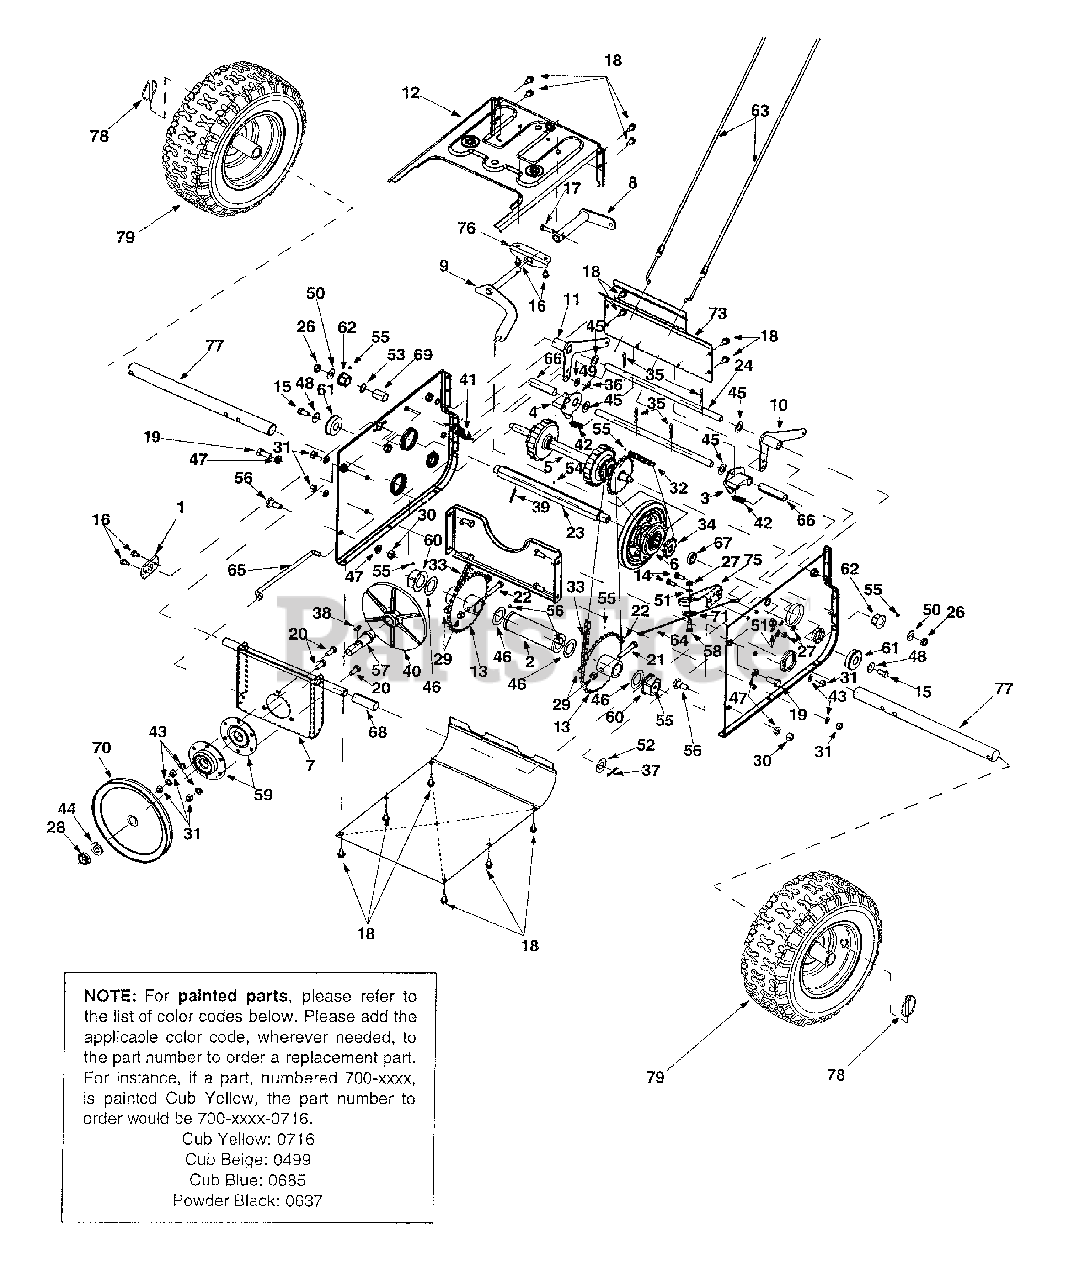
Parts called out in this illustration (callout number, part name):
1	Support Bracket: Pivot
2	Bush Assembly
3	Dogg Assembly LH
4	Dogg Assembly RH
5	Shift Assembly
6	Wheel Bearing Assembly
10	Auger Actuator Bracket Assy.
14	Hex Screw 1/4-28 x .625"
15	Hex Screw 5/16-18 x .625"
16	TT Screw 1/4-20 x .5"
17	TT Screw 1/4-20 x 1"
18	TT Screw 1/4-20 x .625"
19	Hex Screw 3/8-16 x .880"
20	Hex Screw 5/16-18 x .75"
21	Hex Screw 5/16-18 x 2"
22	Hex Screw 5/16-18 x 1.75"
23	Hex Shaft: Drive
24	Actuator Shaft
27	Hex Nut 1/4-28
28	Jam Lock Nut
29	Hex Lock Nut
30	Hex Nut 3/8-16
31	Hex Nut 5/16-18
35	Hairpin Clip
36	Hairpin Clip
37	Cotter Pin
38	Key
39	Roll Pin
40	Drive Plate
41	Extension Spring
42	Extension Spring
43	Lock Washer 5/16
44	Lock Washer 5/8
45	Flat Washer
46	Flat Washer
47	Lock Washer
48	Beleville Washer
49	Flat Washer
50	Flat Washer
51	Lock Washer
52	Flat Washer
53	Flat Washer
54	Lubricant
56	Shoulder Screw
57	Spindle: Drive Plate
58	Shoulder Screw 1/4-28 x .375"
59	Bearing Housing Assembly
60	Flange Bearing
61	Ball Bearing
62	Hex Flange Bearing
63	Steer Cable
64	Idler Cable: Auger
65	Clutch Rod: Drive
66	Split Spacer
67	Spacer
68	Split Spacer
70	Drive Pulley
71	Roller Cable
77	Axle: Wheel
